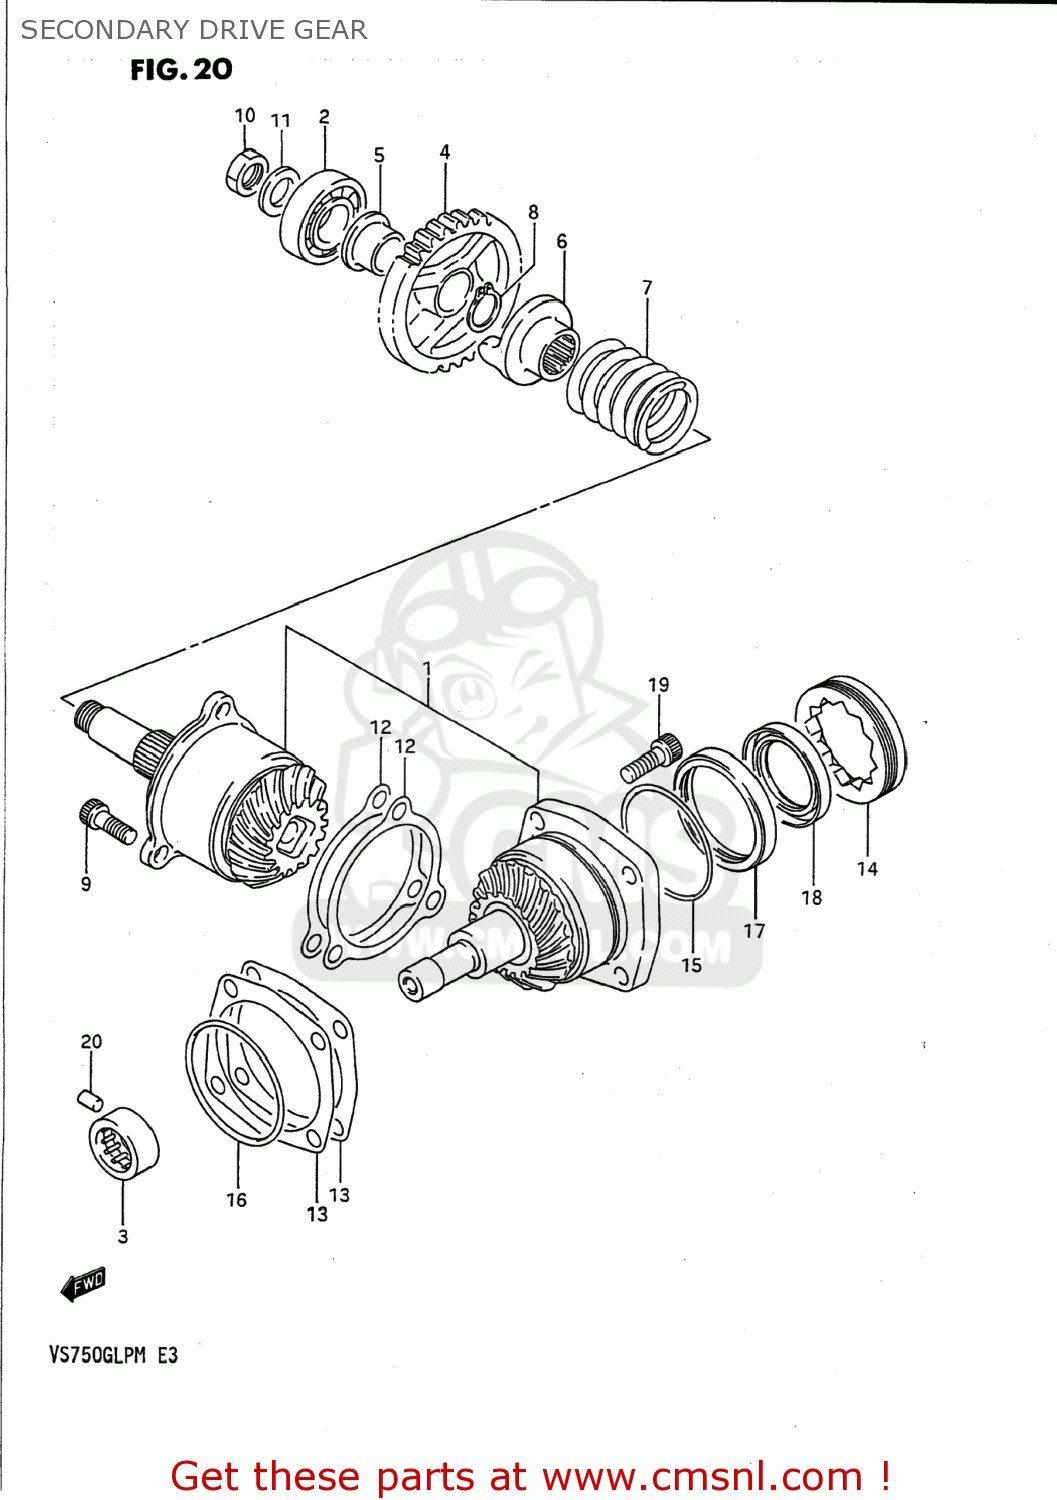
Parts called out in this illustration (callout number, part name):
1	GEAR & HOUSING SET,SECONDARY
2	BEARING(20X52X15)
3	BEARING(20X34X16)
4	GEAR,REDUCTION DRIVEN(NT:30)
5	BUSH,REDUCTION DRIVEN GEAR
6	DOG,OUTPUT CAM
7	SPRING
8	CIRCLIP,21MM
9	BOLT
10	NUT
11	WASHER(16X29X4)
12	SHIM,SECONDARY DRIVE
13	SHIM,SECONDARY DRIVEN HOUSING
14	STOPPER,SEC DRIVEN BEARING
15	O RING(D:1.2,ID:59.6)
16	O RING(D:2.1,ID:66.2)
17	HOUSING,OIL SEAL
18	SEAL,OIL(38X54X8.5)
19	BOLT
20	PIN
